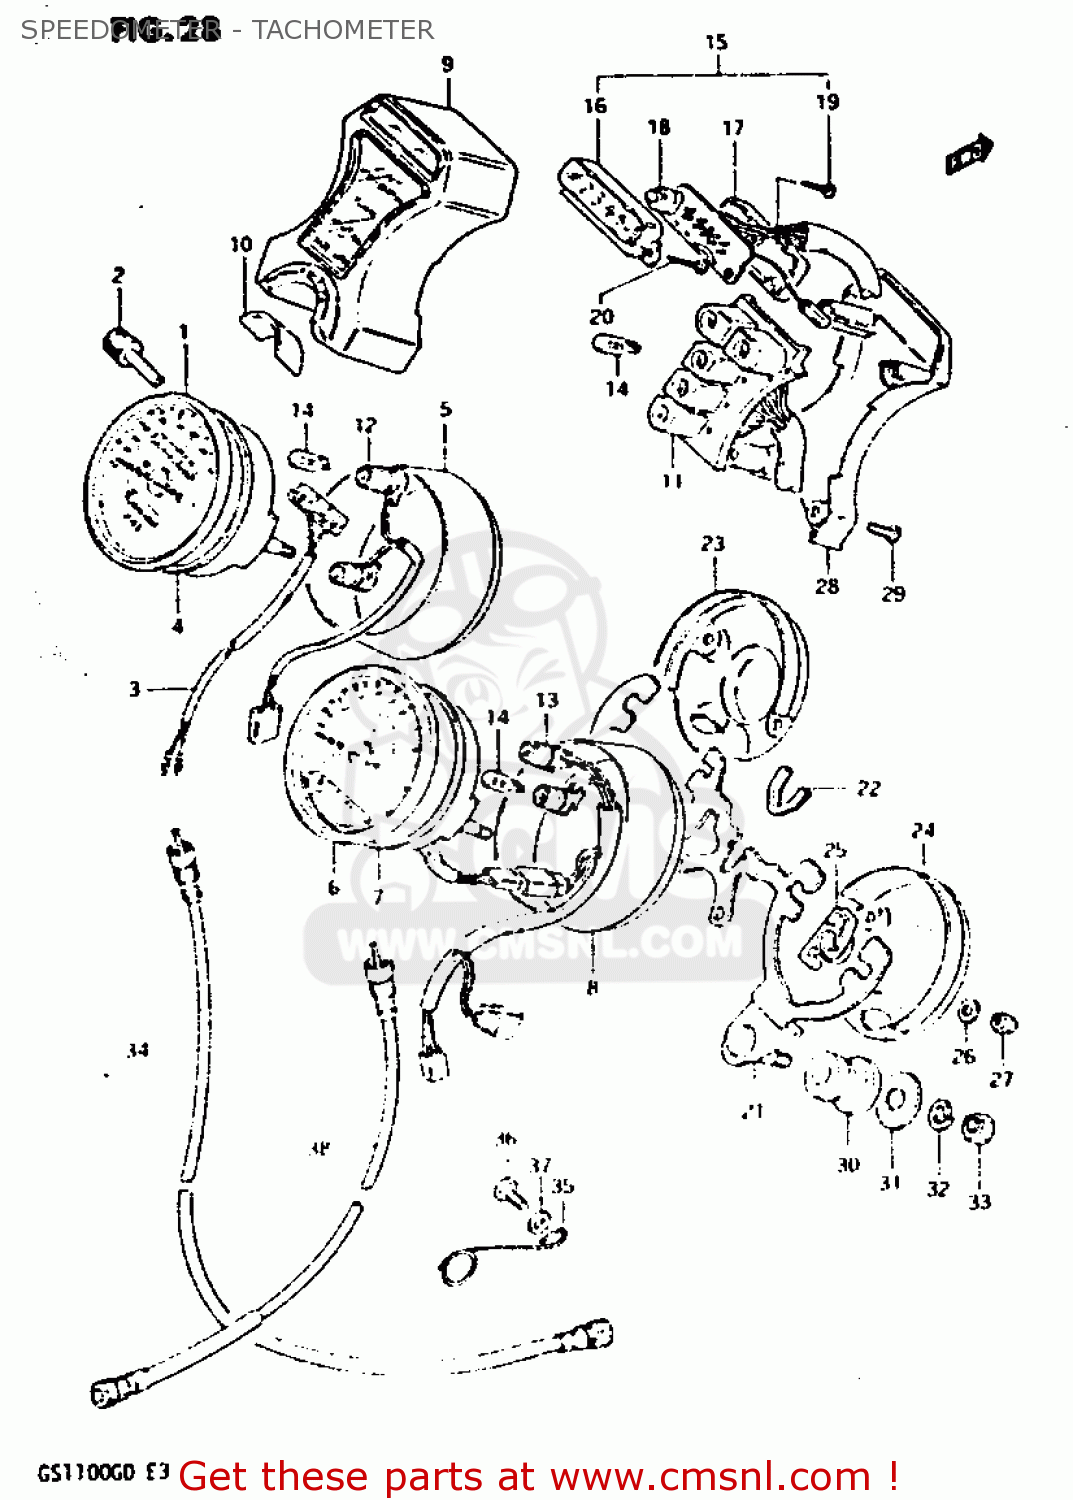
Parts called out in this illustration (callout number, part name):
1	METER,SPEEDOMETER (KM/MPH)
2	KNOB,TRIP
3	WIRE,LEAD
4	CUSHION,METER
5	COVER,SPEEDOMETER
6	METER,TACHOMETER
7	CUSHION,METER
8	COVER,TACHOMETER
9	CASE,PILOT BOX
10	SEAL,IGNITION SWITCH
11	SOCKET,PILOT BOX
12	SOCKET,SPEEDOMETER
13	SOCKET,TACHOMETER
14	BULB(12V3.4W,T10)
15	INDICATOR ASSEMBLY,GEAR POSITION
16	CASE,GEAR INDICATOR
17	COVER,LWR
18	BULB(14V1.12W)
19	SCREW,GEAR INDICATOR
20	SCREW
21	BRACKET,COMBINATION METER
22	BRACKET,COVER
23	COVER,METER,UNDER
24	COVER,TACHOMETER,UNDER
25	CUSHION
26	WASHER
27	NUT
28	COVER,PILOT BOX LWR
29	SCREW,PILOT BULB CASE
30	CUSHION,METER BRACKET
31	WASHER (8.5X20X1.6)
32	WASHER,LOCK,8.
33	NUT
34	CABLE ASSEMBLY,SPEEDOMETER
35	CLAMP,SPEEDOMETER CABLE
36	BOLT
37	WASHER
38	CABLE ASSEMBLY,TACHOMETER
